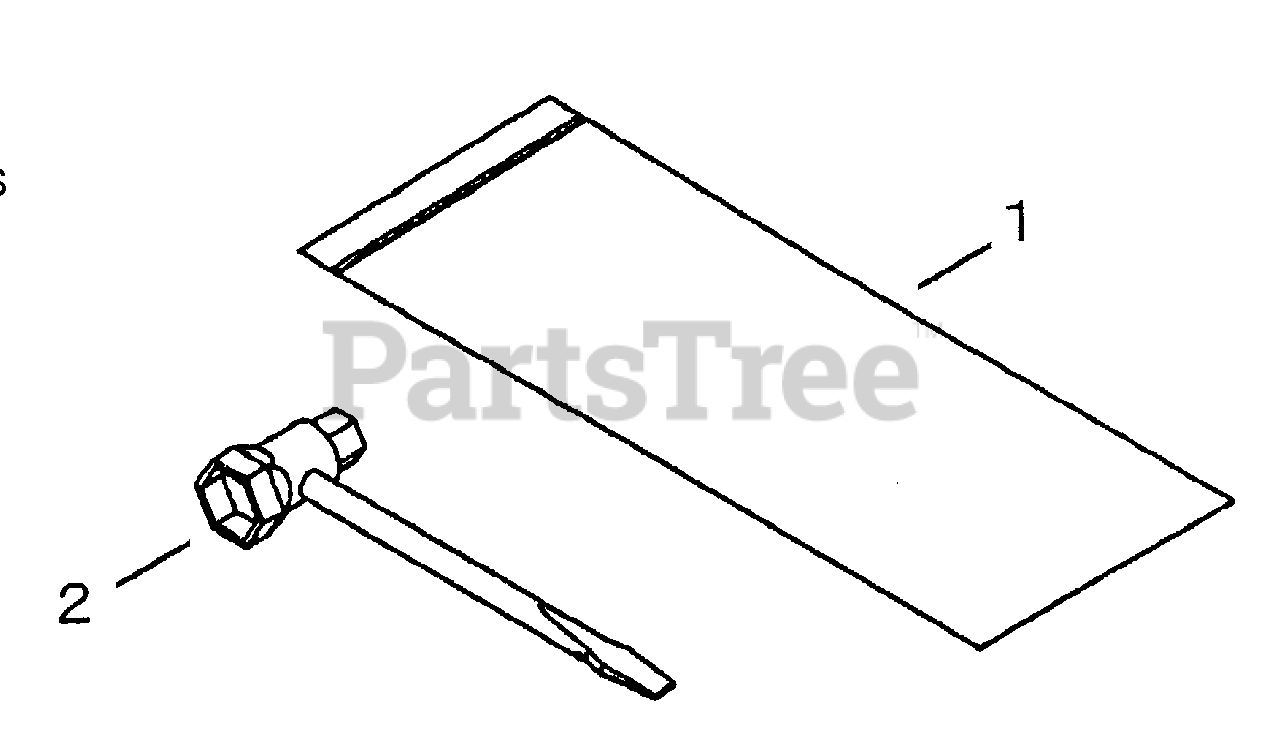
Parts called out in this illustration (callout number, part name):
1	BAG, TOOL
2	T-WRENCH 13×19 MM
3	WRENCH, ALLEN 4 MM
